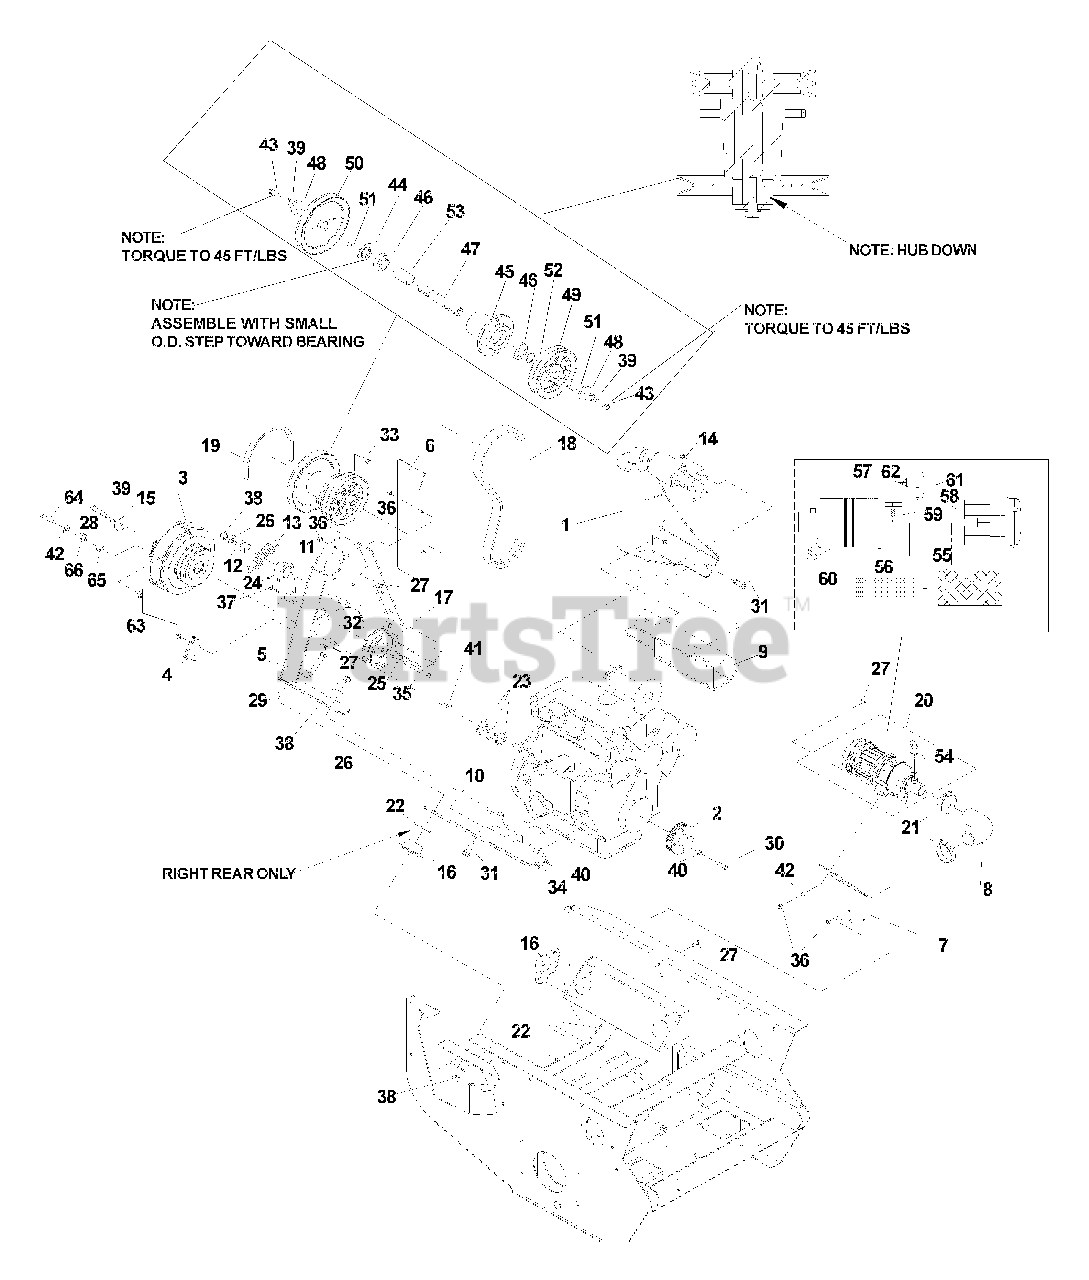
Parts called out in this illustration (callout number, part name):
2	Sheave, engine
4	Restraint
5	Jack mount
6	Shield, heat
7	Bracket, air filter
9	Engine mount, left
10	Engine mount, right
14	Nut, M8-1.25, stover top lock
15	Washer, heavy
16	Isolator mount, engine
18	Belt, primary
19	Belt, mule
20	Air filter assembly
22	Washer, heavy
23	Bushing, machine, 1 1/8 x 10 ga.
25	Washer, 3/8,SAE
26	Washer, 1/2
27	Bolt, 5/16-18 x 3/4
28	Bolt, 7/16- 20 x 2 1/2
29	Bolt, 1/2-13 x 2 3/4
30	Bolt, M8-1.25 x 35
31	Bolt, 1/2-13 x 1 1/4, serrated head
32	Bolt, 1/2-13 x 2 1/2
33	Bolt, 5/16-18 x 1
34	Bolt, M8 x 1.25 x 20
35	Bolt, 3/8-16 x 3 1/2
36	Nut, 5/16-18, nyloc
37	Nut, 3/8-16, nyloc
38	Nut, 1/2-13, nyloc
39	Lockwasher, 7/16
40	Lockwasher, 5/16
41	Key, 1/4 sq. x 2 1/2
42	Washer, 5/16
43	Bolt, 7/16-20 x 1 1/2
44	Combo spacer
46	Bearing
48	Washer, heavy
51	Key, 1/4" sq. x 1 1/8"
52	Machine bushing, 18 ga
54	Indicator, air filter
55	Air filter
56	Safety element
58	Precleaner assembly
59	Mounting bracket
63	Nut, 5/16C
64	HCS, 5/16C X 1 1/4
